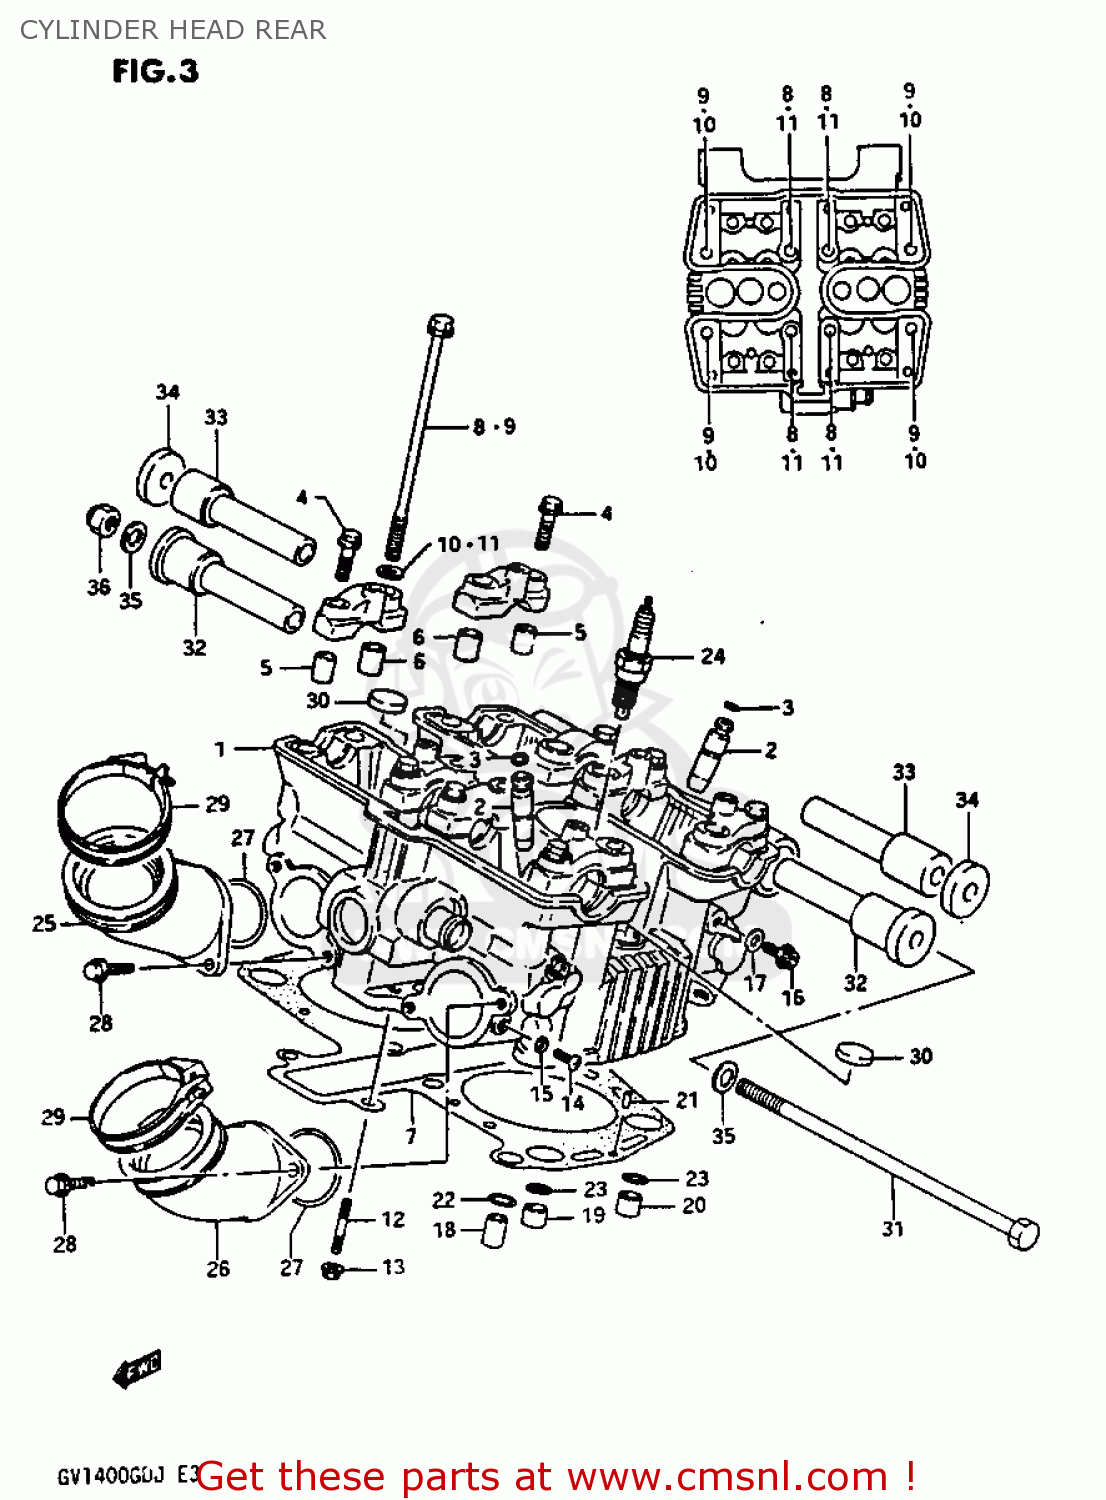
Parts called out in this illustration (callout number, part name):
1	HEAD ASSEMBLY,CYLINDER,REAR
2	GUIDE,VALVE
3	RING,SNAP
4	BOLT
5	PIN (11X20)(SUS)
6	PIN(10.4X13X22)
7	GASKET,CYLINDER HEAD,REAR (MCA)
8	BOLT
9	BOLT
10	WASHER
11	WASHER (10X20X2.3)
12	STUD 6X25
13	NUT 6MM
14	SCREW
15	GASKET(5.3X9.3X1.2) (NAS)
16	BOLT
17	GASKET(6.2X13X1.2) (NAS)
18	PIN
19	PIPE
20	PIN
21	PIN
22	O RING(D:1.9,ID:8.6)
23	O RING(D:1.9,ID:12.6)
24	SPARK PLUG
25	PIPE,INTAKE
26	PIPE,INTAKE
27	O-RING (D:2.4 ID:39.7)
28	BOLT 6X20
29	CLAMP,PIPE
30	PLUG
31	BOLT
32	SPACER,ENGINE MOUNT
33	SPACER,ENGINE MOUNT
34	SPACER,ENGINE MOUNTING NO.2
35	WASHER 10MM
36	NUT
